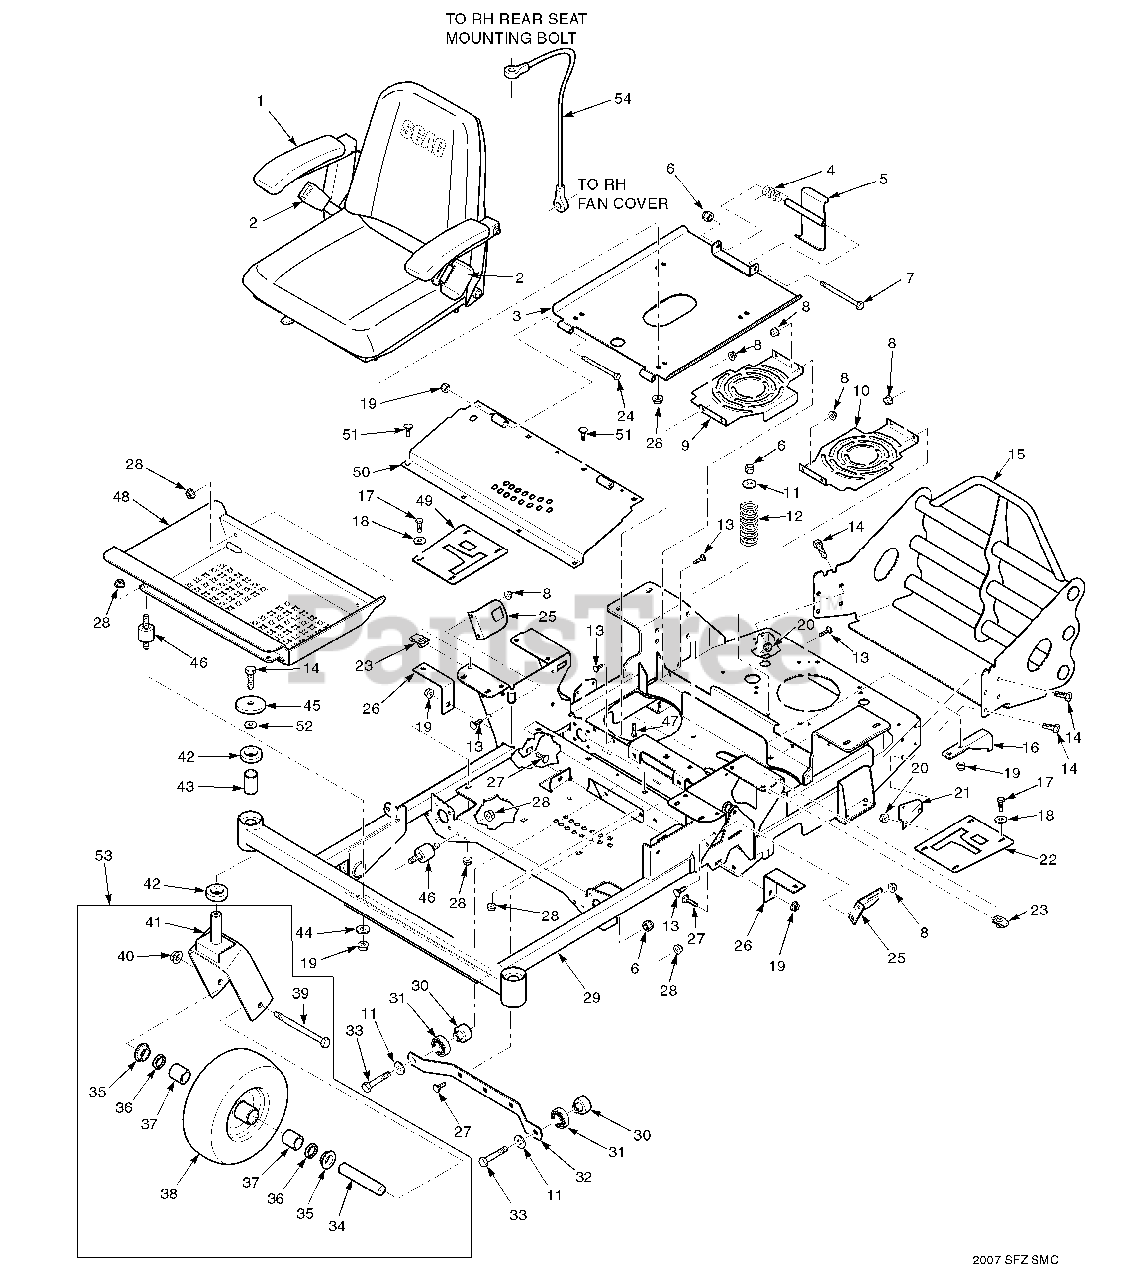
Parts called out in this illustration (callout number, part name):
1	Seat Assembly
2	Seat Belt Assembly, Retractable
3	Seat Base w/decal
4	Spring, Seat Latch
5	Seat Latch
6	Nut, Elastic Stop 3/8-16
7	Bolt, Hex Head 3/8-16 x 6"
8	Nut, Serrated Flange 1/4-20
9	Cover, Fan RH
10	Cover, Fan LH
11	Flatwasher, 3/8-.391 x .938 x .105
12	Spring, Seat
13	Bolt, Carriage 1/4-20 x 1/2"
14	Bolt, Hex Head 3/8-16 x 1"
15	Rear Bumper
16	Bracket, Anti-Rotation
17	Bolt, Hex Head 1/4-20 x 1"
18	Flatwasher, 1/4-.312 x .750 x .065
19	Nut, Elastic Stop 5/16-18
20	Nut, Serrated Flange 3/8-16
21	Bracket, Dump Valve
22	Control Plate LH
23	U-Nut 1/4-20
24	Bolt, Hex Head 5/16-18 x 3-3/4"
25	Bracket, Switch Mount
26	Bracket, Tank Mount
27	Bolt, Carriage 5/16-18 x 3/4"
28	Nut, Serrated Flange 5/16-18
29	Main Frame w/Decals
30	Spacer, Bearing
31	Bearing
32	Support, Deck Guide
33	Bolt, Hex Head 3/8-16 x 2-1/2"
34	Sleeve, Front Caster Wheel
35	Bearing
36	Seal, 1 x 1.375 x .25
37	Bearing
38	Caster Wheel Assembly
39	Bolt, Hex Head 1/2-13 x 6-1/2"
40	Nut, Elastic Stop 1/2-13
41	Yoke, Caster Wheel
42	Bearing
43	Spacer, Caster Bearing
44	Flatwasher, 5/16-.375 x .875 x .083
45	Flatwasher, 3/8-.406 x 2.25 x .188
46	Rubber Isolator
47	Bolt, Carriage 3/8-16 x 1-1/4"
48	Foot Plate Weldment
49	Control Plate RH
50	Weldment, Deck Lift Cover
51	Bolt, Carriage 5/16-18 x 1/2"
52	Flatwasher, 7/16-.500 x 1.250 x .083
53	Caster Wheel Assembly w/Yoke
54	Cable, Seat Stop
